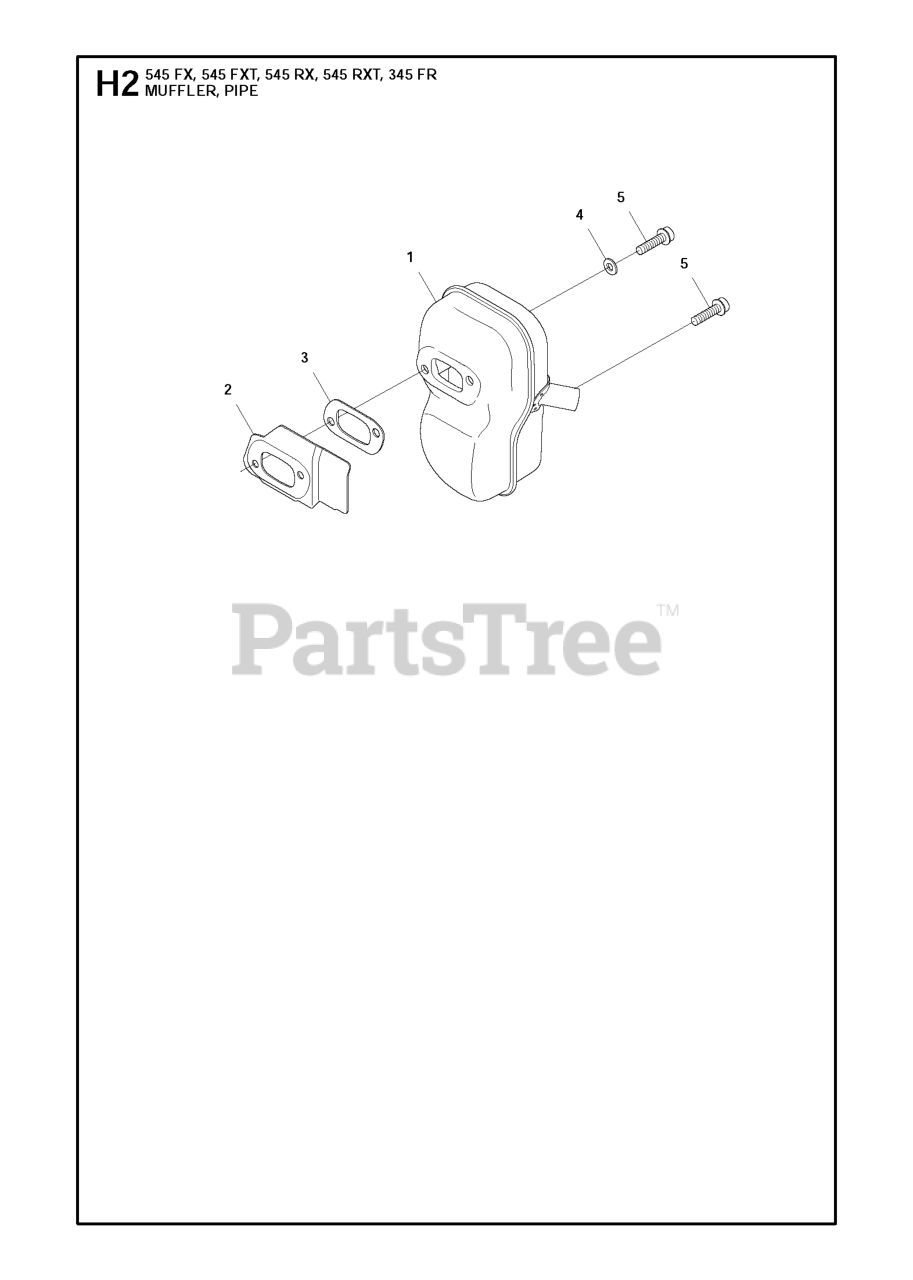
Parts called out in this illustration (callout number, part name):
1	MUFFLER KIT NEW BAFFLE
2	HEAT DEFLECTOR
4	DOUBLE WASHER
